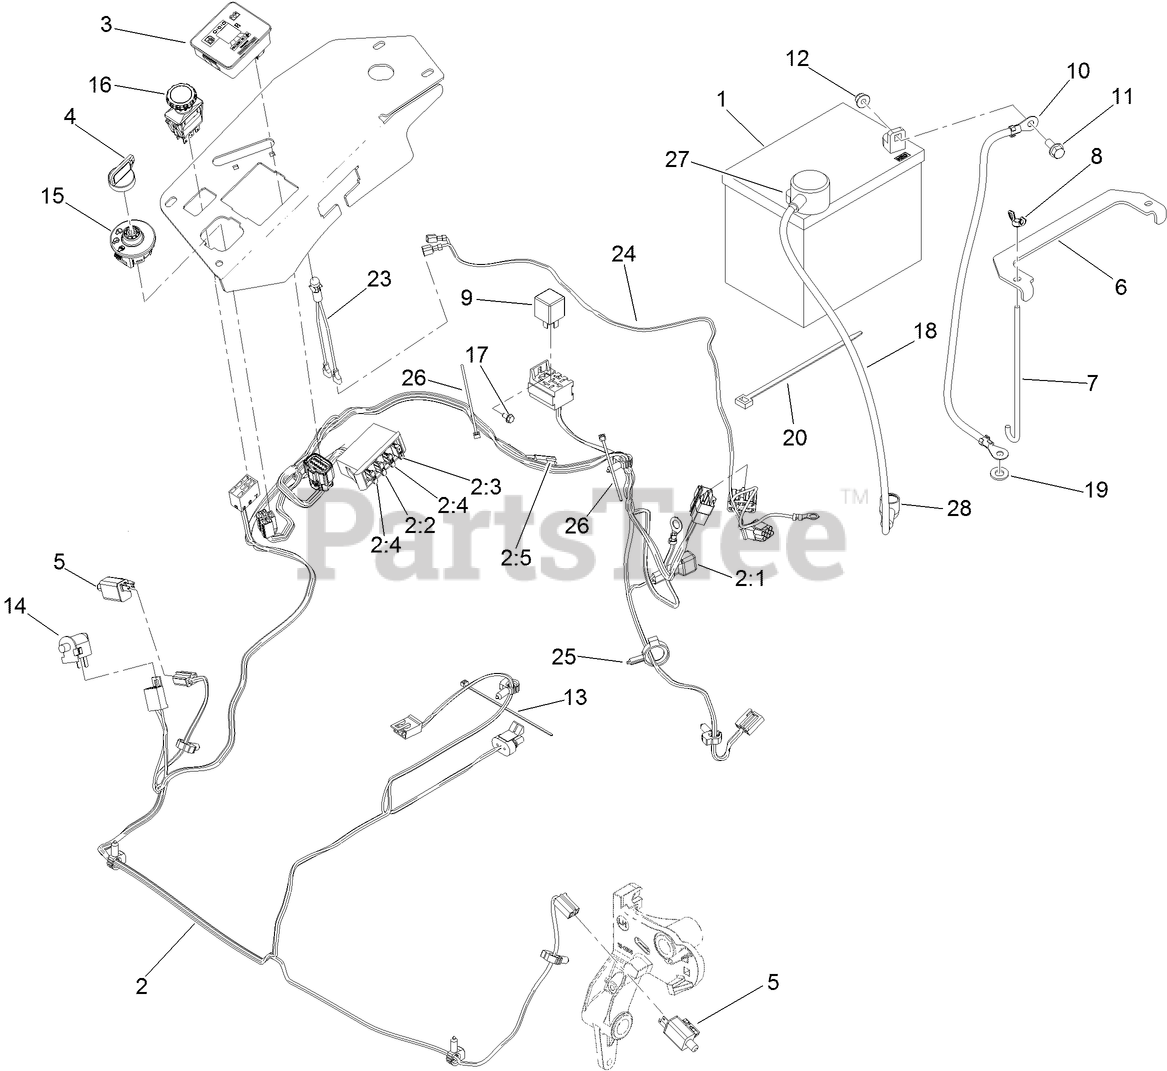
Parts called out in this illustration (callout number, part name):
1	BATTERY-DRY
2	HARNESS-WIRE, MAIN
2:2	FUSE-BLADE, 10 AMP
2:3	FUSE-BLADE, 15 AMP
2:4	FUSE-BLADE, 25 AMP
2:5	CAP-PLUG
3	FUEL/HOUR METER ASM
4	KEY-IGNITION
5	SWITCH
6	STRAP-TIE DOWN, BATTERY
7	BOLT-HOLDDOWN
8	WINGNUT
10	CABLE-BATTERY, NEGATIVE
11	SCREW-HHF
12	NUT-HF, NI
13	TIE-CABLE
14	SWITCH-BAIL
15	SWITCH-IGNITION
16	SWITCH-PTO, 10 AMP
17	SCREW-HWH
18	CABLE-BATTERY, POSITIVE
19	WASHER-FLAT
20	TIE-PLASTIC
23	INDICATOR-LED, RED
24	HARNESS-LIGHT, INDICATOR
25	CLAMP-HOSE
26	TIE-CABLE
27	INSULATOR-BATTERY
28	INSULATOR-SOLENOID
